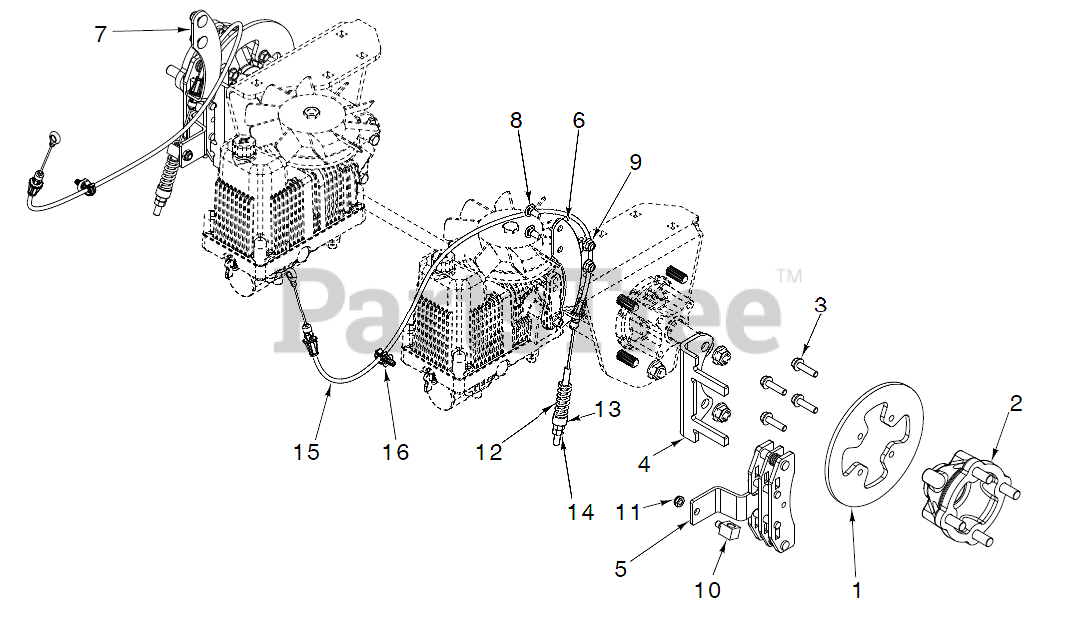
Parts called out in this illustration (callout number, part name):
1	Rotors
2	Hubs
3	Bolts
4	Brackets
5	Brakes
6	Brackets
7	Brackets
8	GSPW Bolts
9	NUT HEXAGON FLANGE 5/16-18 ST
10	Swivels
11	Nuts
12	Springs
13	SPACER
14	Hardware
15	Cables
16	CABLE, 1/4 BLACK FIR TREE
